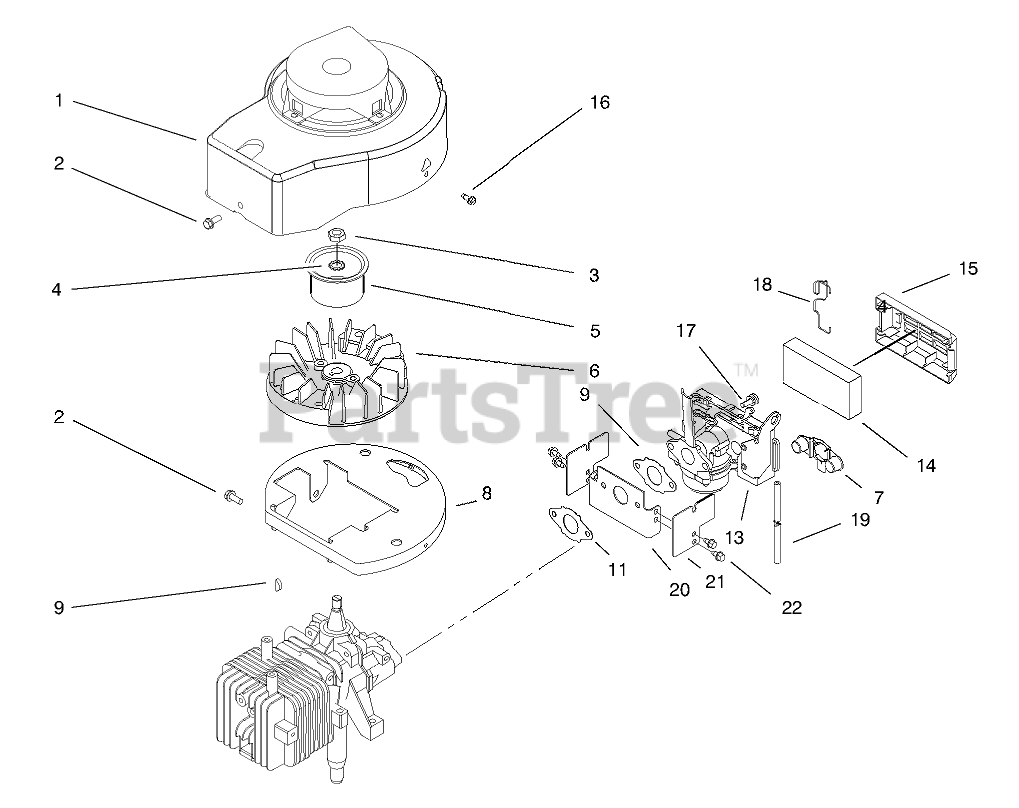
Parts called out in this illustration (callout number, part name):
1	SHROUD
2	SCREW
4	WASHER-LOCK
5	HUB-STARTER V
6	FLYWHEEL(MACH) V
7	SHIELD-FUEL V
8	Base-Shroud
11	GASKET-CARB VF
13	CARBURETOR ASM
14	ELEMENT-AIR FIL VF
15	COVER-AIR FIL. V
16	SCREW VF
17	SCREW
18	RETAINER-COVER, FILTER
19	HOSE-PRIMER
20	SHIELD-CARB V INTL
21	SHIELD- GOV. V INTL
22	SCREW V
